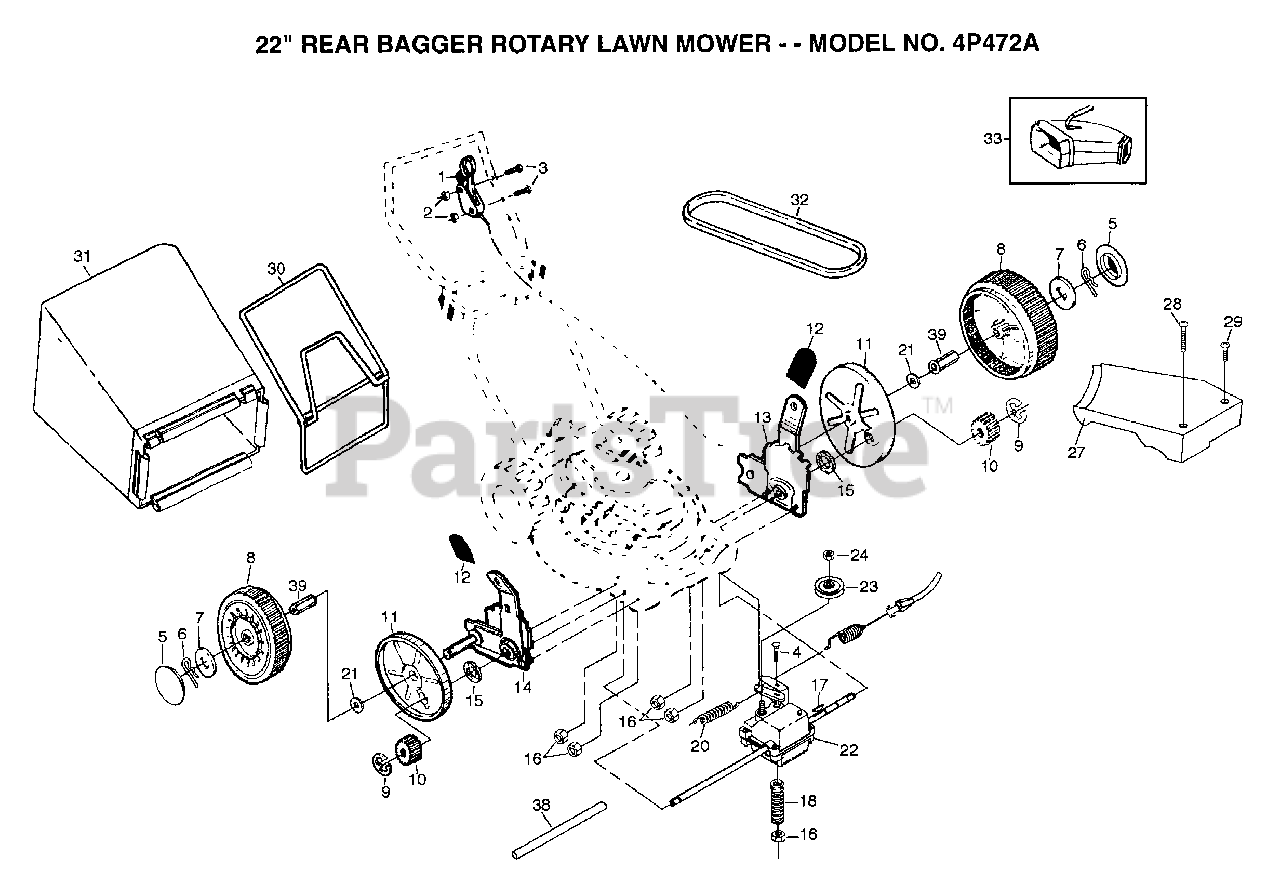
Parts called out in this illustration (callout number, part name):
1	CONTROL.DRIVE
2	LOCKNUT
3	SCREW
4	BOLT.1/4-20X2.0
5	HUB CAP
6	RETAINER CLIP PM
7	WASHER
8	WHEEL.8X2.LP.PR
9	E-RING.7/16.RE.
10	PINION.GEAR
11	DUST SHROUD PM
12	KNOB PM
15	WASHER PM
17	HI PRO KEY
18	SPRING.TENSION
20	SPRING
21	WASHER FLUT
23	PULLEY.DRIVEN
24	LOCKNUT
27	"COVER.DRIVE 22""RD"
30	CATCHER FRAME
31	GRASS BAG
38	DRV SHAFT TUBE PM
39	BUSHING.HEX
